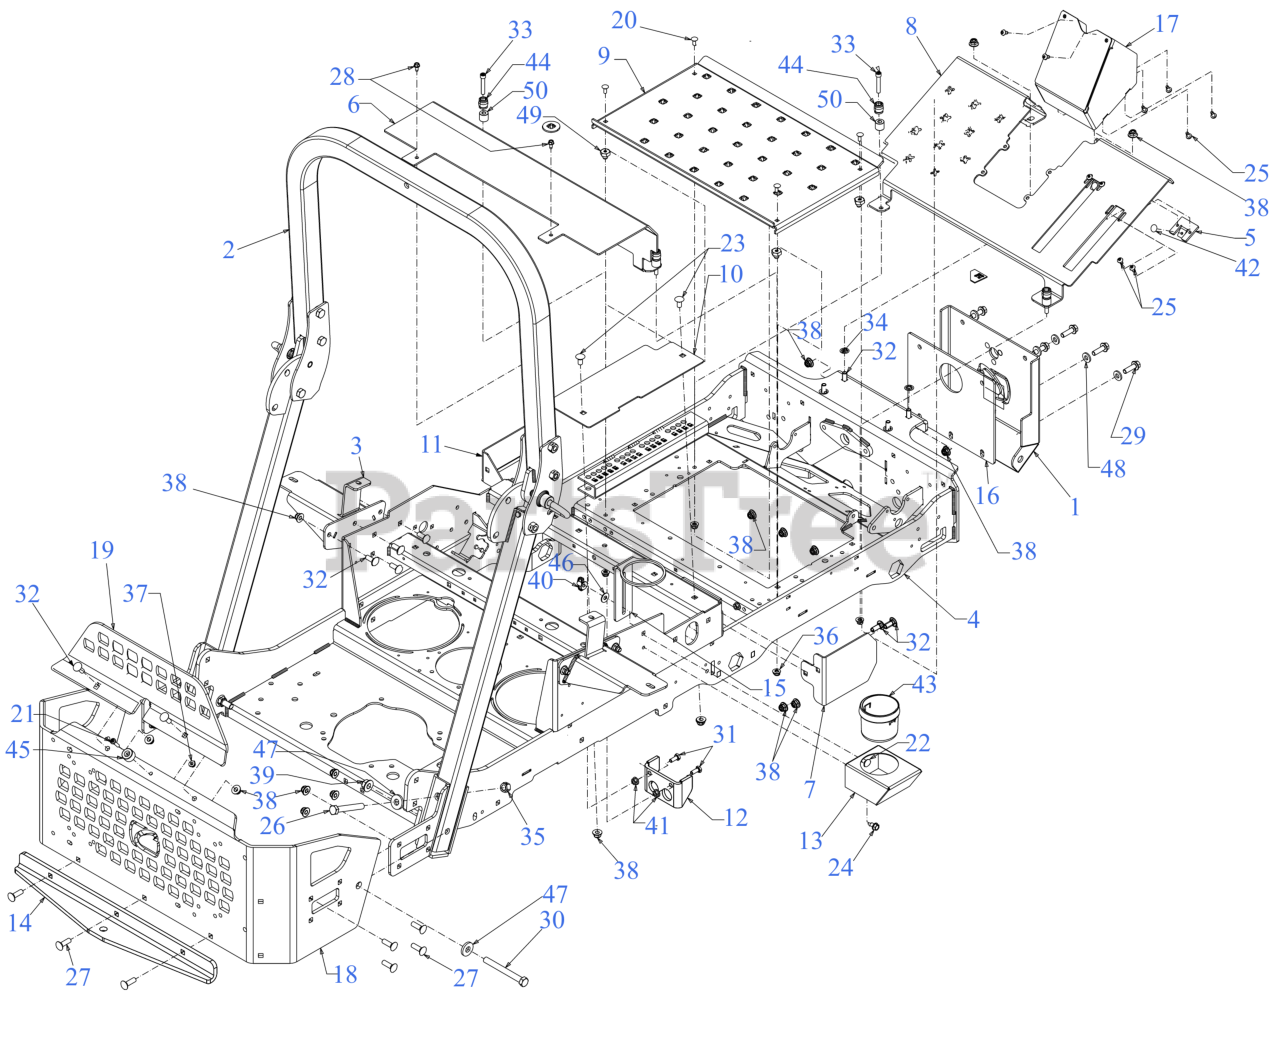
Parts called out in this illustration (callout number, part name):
2	PRO Z ROPS KIT
3	FUEL TANK MOUNT
4	FRAME
5	REVERSE PEDAL STOP BRACKET
6	SEAT BOX COVER
8	FRONT PEDAL COVER
11	SEAT BOX END COVER (LH)
16	FRONT MOUNTING PLATE SPACER
17	EPS COLUMN COVER
18	BUMPER (LOWER RR)
19	BUMPER (UPPER RR)
20	CARRIAGE BOLT 1/4-20 x .62
21	MACHINE SCREW 1/4-20:1
22	CARRIAGE BOLT 5/16-18 x 1.00
23	CARRIAGE BOLT 3/8-16 x .750 GR5
24	SCREW 5/16-18 x .750
25	SCREW 1/4-20 x .5
26	SCREW 1/2-20 x 3.50 GR5
27	CARRIAGE BOLT 3/8-16 X1.25 GR5
28	SCREW 1/4-20 X.500
29	SCREW 3/8-16 x 1.25 GR5
30	SCREW 1/2-13 x 4.5 GR 5
31	SCREW 5/16-18 x .75 GR5
32	CARRIAGE BOLT 3/8-16 x 1.00 GR5
33	SCREW 5/16-18X1.75 GR5
36	FLANGE LOCK NUT 5/16-18
37	FLANGE LOCK NUT
40	WING NUT 5/16-18
41	FLANGE NUT
42	RATCHET CLIP
44	RADIAL BUMPER
46	FLAT WASHER
47	FLAT WASHER .531 x 1.25 x .181
48	FLAT WASHER
49	SHOULDER SPACER
